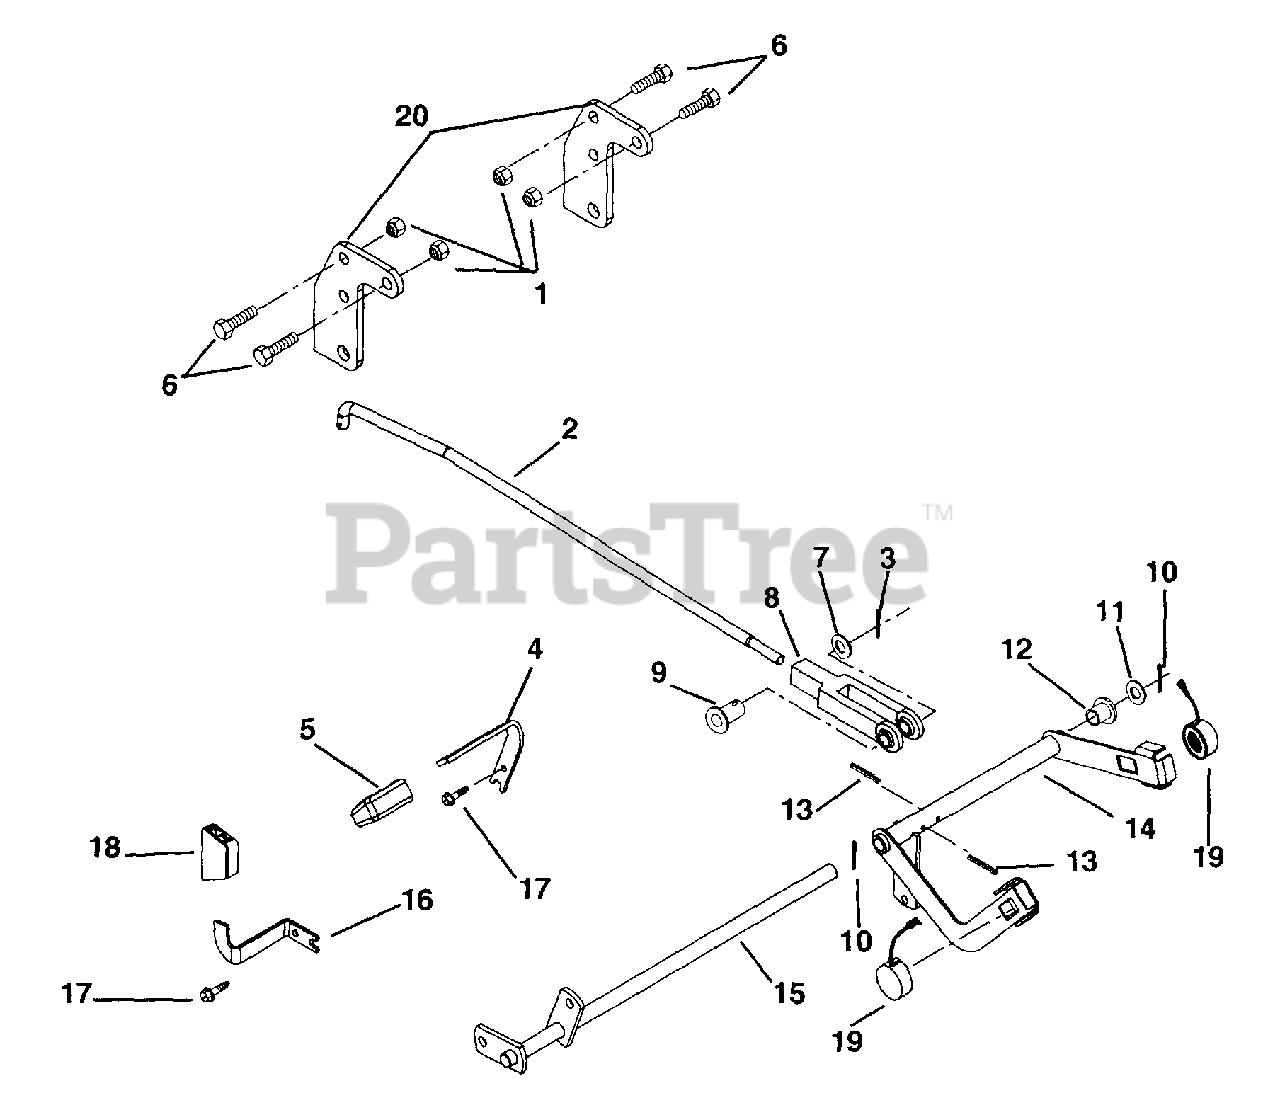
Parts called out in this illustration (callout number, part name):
1	Nut-Locking .375-16
2	Rod-Shift
3	Pin-Cotter .09 x .75
4	Pedal-Forward
5	Cover-Pedal-Forward
6	Bolt-Hex .38-16 x .75 Grade 5
7	Washer-Flat-Steel .390 x .750 x .125
8	Yoke .31-24 x 2.25
9	Pin-Clevis .312 x .822
10	Pin-Cotter .12 x 1.0
11	Washer-Flat-Steel .520 x .827 x .062
12	Bushing-Flange .515 x .750 x .745 x 1.00 Nylon
13	Pin-Groove .188 x 1.25
14	Assembly-Forward/Reverse Pedal
15	Shaft Pedal
16	Pedal-Reverse
17	Screw-Tapping .375-16 x 1.00
18	Cover-Pedal-Reverse
19	Magnet-Locking Electric
20	Bracket-Hanger
